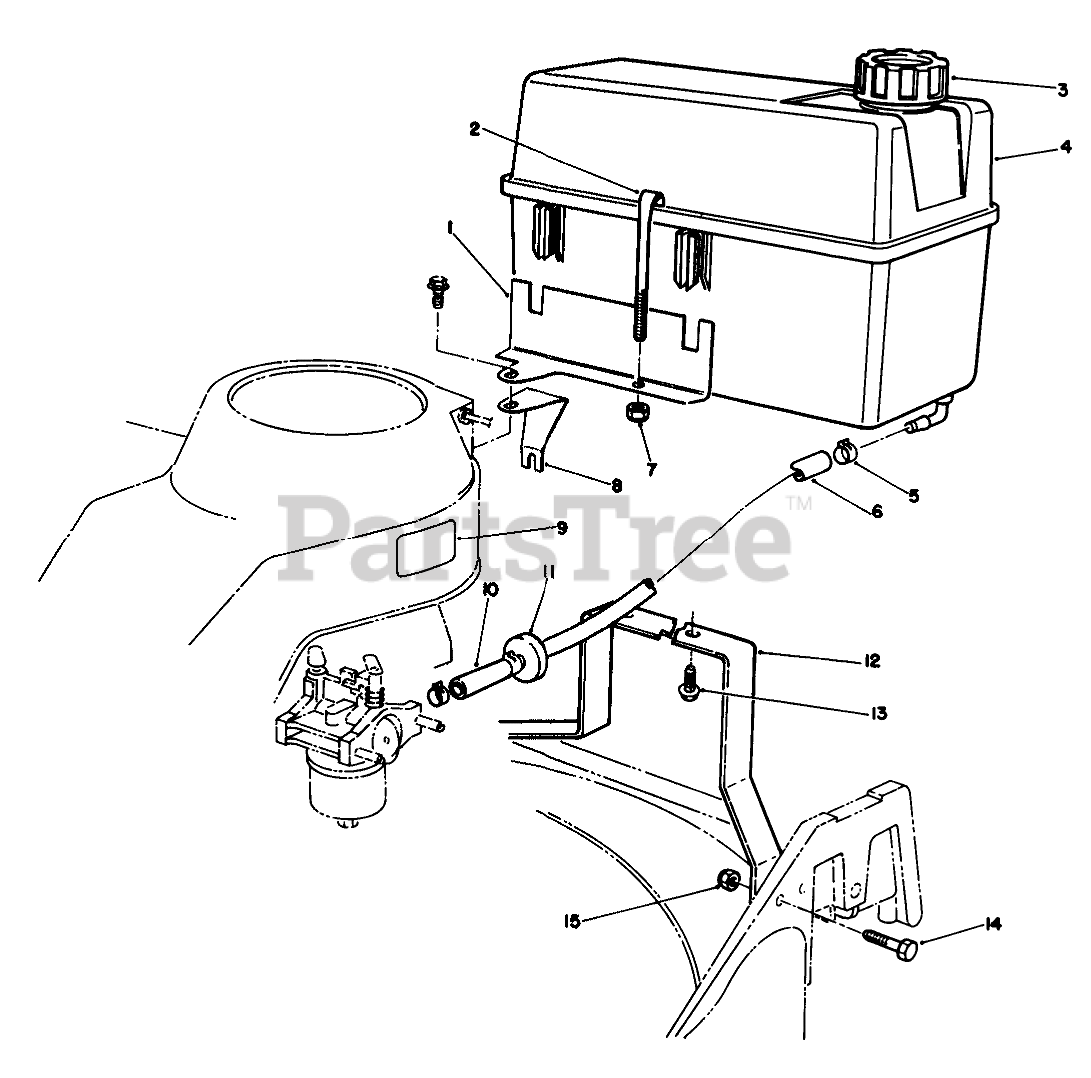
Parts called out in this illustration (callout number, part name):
1	Bracket Tank
2	RETAINER - FUEL TANK
3	GAS CAP ASM
4	Tank-Gas
5	CLAMP-FUEL LINE
6	HOSE-FUEL
7	NUT-LOCK, NI
8	Support-Bracket
9	DECAL - FUEL
10	LINE-GAS
11	FILTER-FUEL
12	Base-Tank, Fuel
13	SCREW-HWH
14	SCREW-HH
15	NUT-LOCK, NI
